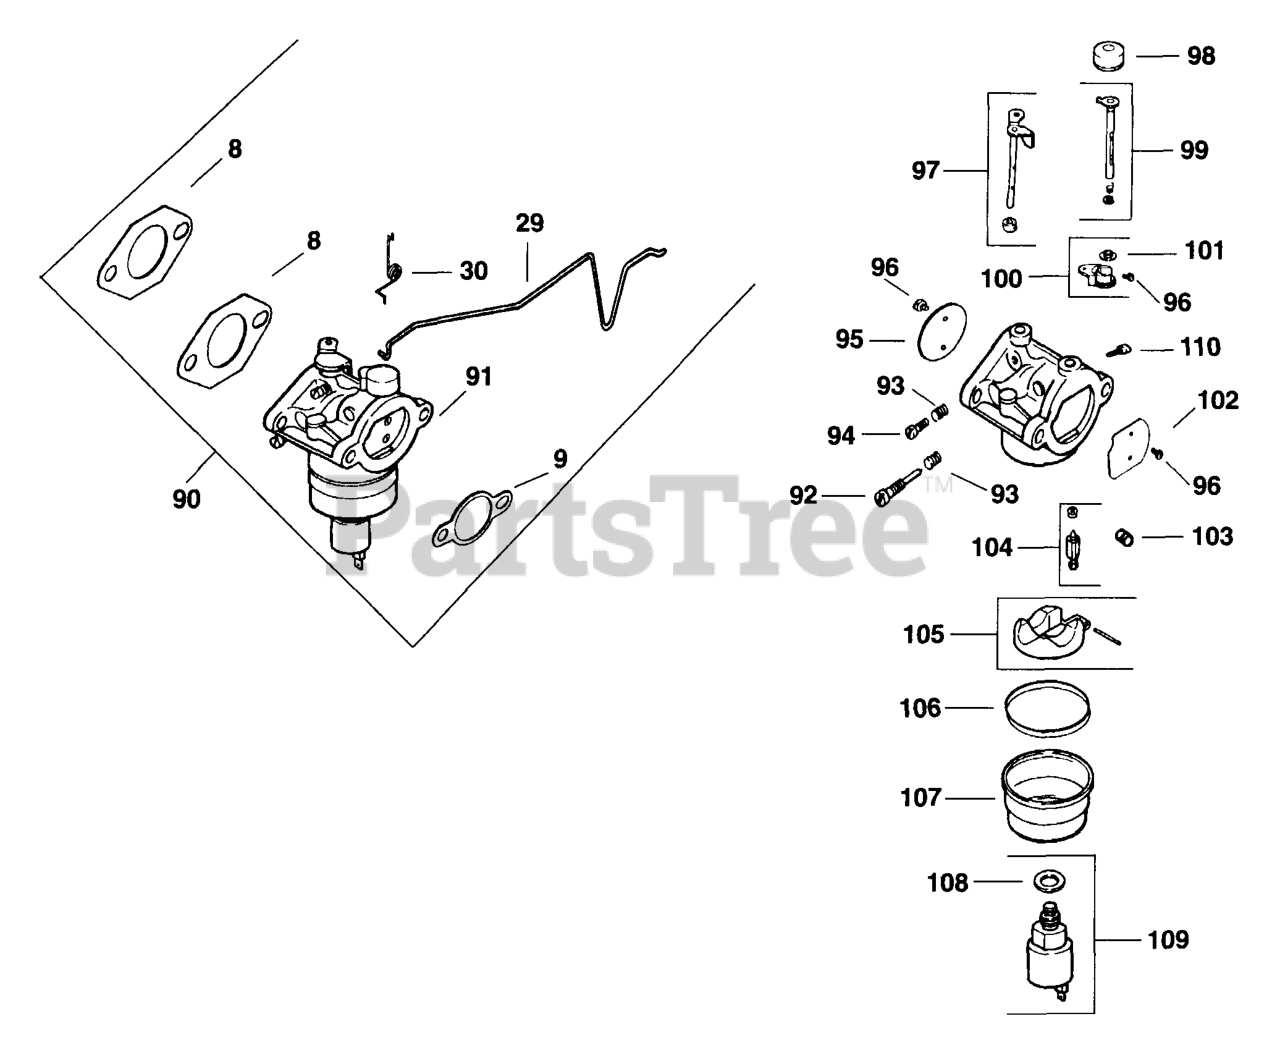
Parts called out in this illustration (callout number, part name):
8	GASKET, CARBURETOR
9	GASKET, AIR CLEANER BASE
29	LINKAGE, CHOKE
90	CARBURETOR - USE 12 853 44
91	Carburetor assembly
92	NEEDLE, IDLE - DISCONTINUED
96	SCREW, VALVE
97	SHAFT, THROTTLE
98	CAP, CHOKE LEVER
99	SHAFT ASSEMBLY, CHOKE - USE 12 757 08-S
100	KIT, CHOKE LEVER REPAIR - USE 12 757 32-S
101	BUSHING, CHOKE
102	PLATE, CHOKE
103	JET, MAIN - DISCONTINUED
104	Needle and Seat
105	KIT, REPAIR FLOAT
106	GASKET, FUEL BOWL
109	KIT, SOLND. FUEL SHUT OFF - USE 12 757 33
1251804-S	LEAD - DISCONTINUED
4151834-S	LEAD
